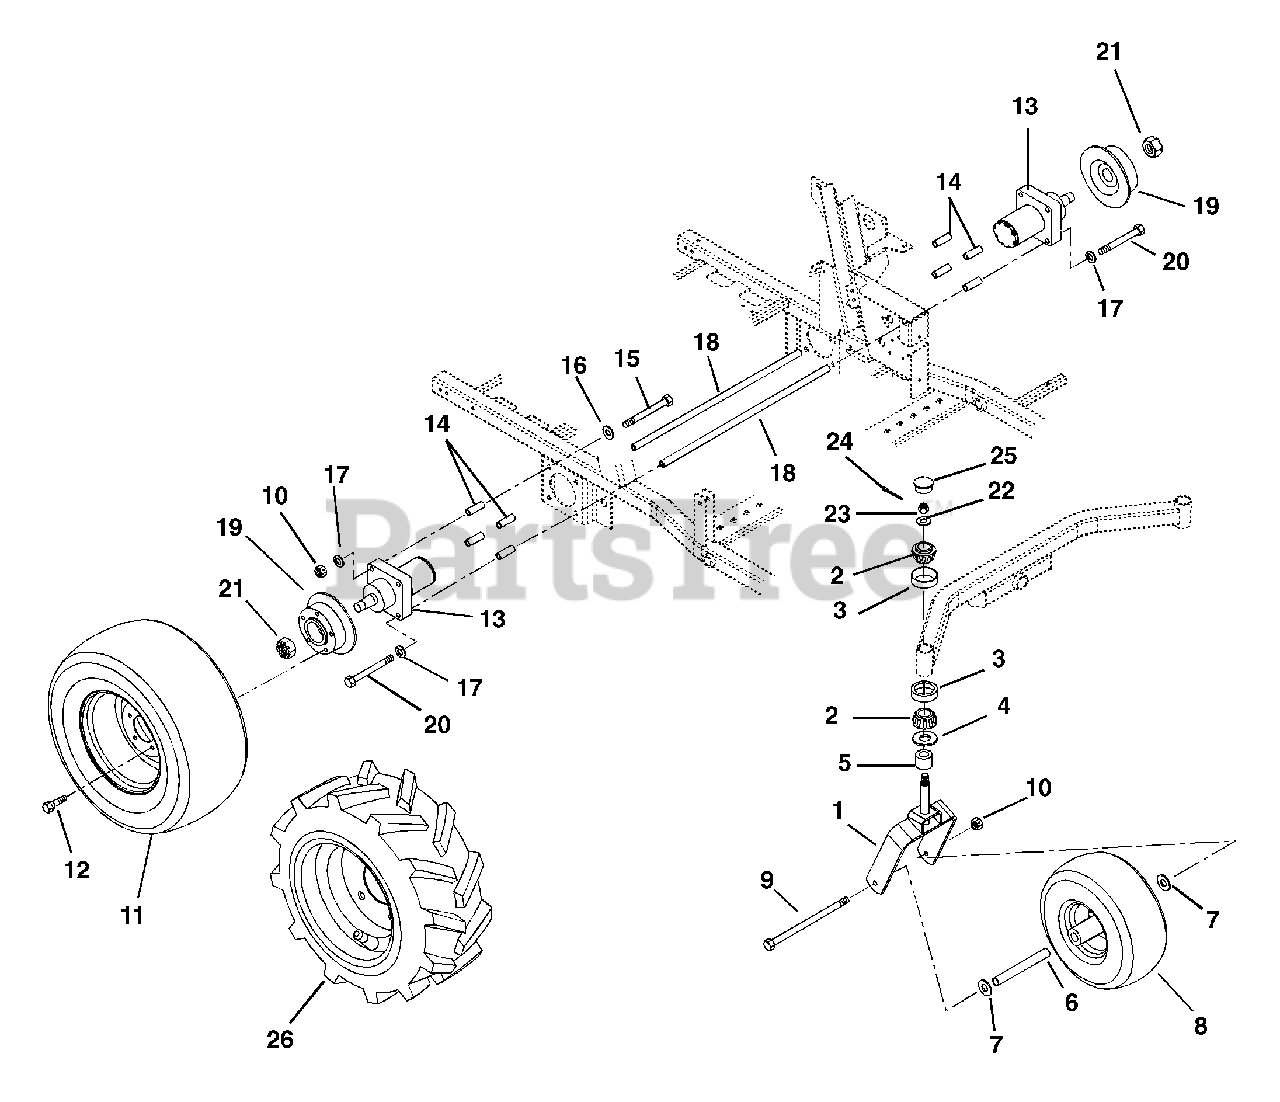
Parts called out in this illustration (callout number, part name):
1	Fork-Front
2	Bearing-Cone w/ Grease
3	Bearing-Cup 1.980 x .420
4	Bearing Seal 1.5 x 2 x .18
5	Spacer, PM, 1.03 I.D. x 1.5 O.D. x .375
6	Spacer-Wheel
7	Washer-Flat-Steel .515 x 1.625 x .250
8	Wheel/Tire Assembly
8	Tire, 15 x 6 - 6
9	Bolt-Hex .50 - 13 x 9.00 Grade 5
10	Nut-Locking-Center .50 - 13
11	Wheel-Tire 23 x 10.50 - 12 Multi-Trac
11	Tire 23 x 10.50
11	Wheel-Tire Assembly 23 x 10 50-12
11	Wheel-Tire 23 x 8.50 Multi-Trac
11	Tire 23 x 8.50
12	Bolt-Lug .50-20 x 1.62
13	Hydraulic Wheel Motor
14	Bushing-Sleeve .513 x .748 x 2.129
15	Bolt-Hex .50 - 13 x 5.00 Grade 5
16	Spacer .500 x .750 x .321
17	Washer-Locking .50 x .125
18	Rod-Motor Connecting
19	Hub and Disc
20	Bolt-Hex .50 - 13 x 4.50 Grade 5
21	Nut -Lock Jam Patch
22	Washer-Flat-Steel .755 x 1.375 x .062
23	Nut-Slotted .75 - 16
24	Pin-Cotter .16 x 1.00
25	Cap-Dust
26	Wheel/Tire Kit, 260Z L. & R.
26	Wheel/Tire-L.H. 23 x 10.5 - 12 Tru Power
26	Wheel/Tire-R.H. 23 x 10.5 - 12 Tru Power
26	Wheel/Tire 23 x 10.50 - 12 Tru Power
